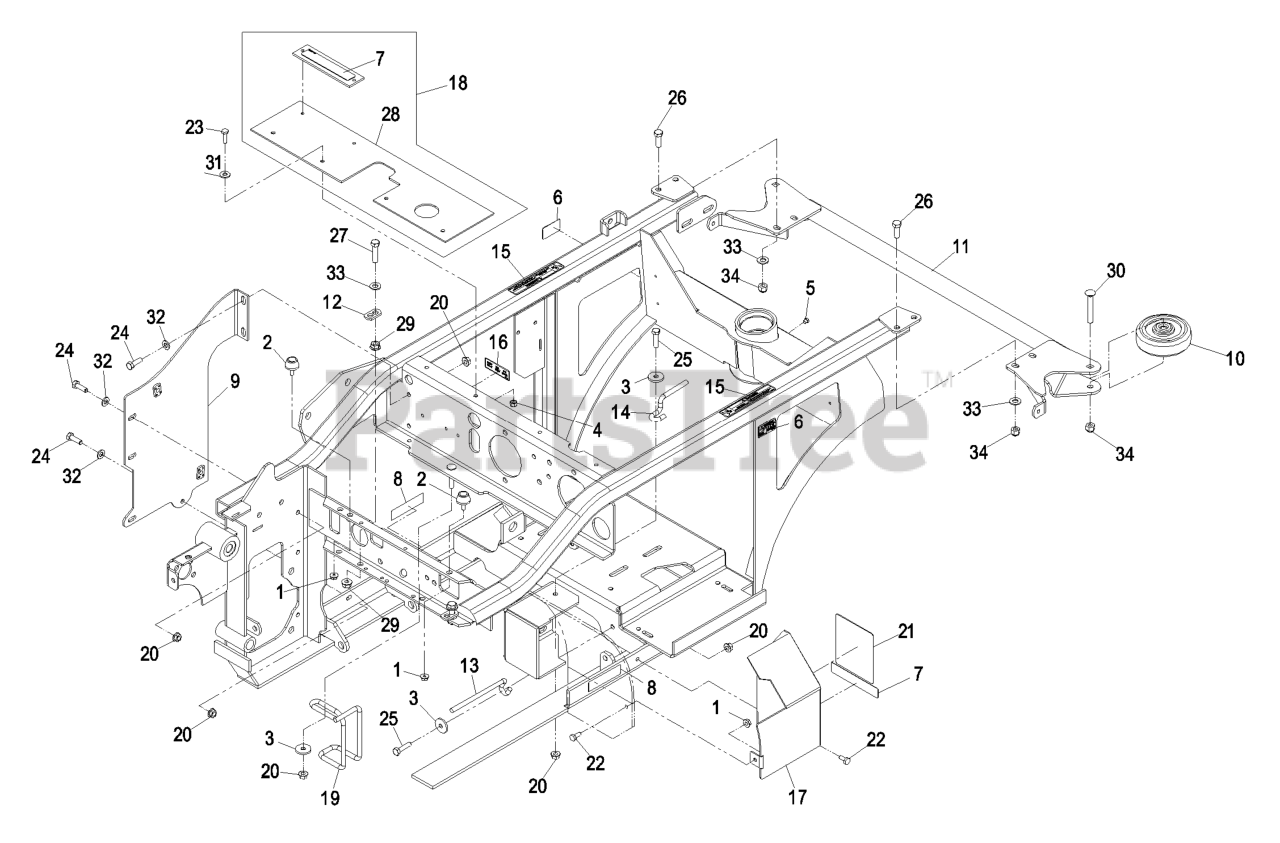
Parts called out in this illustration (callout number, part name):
4	NUT-LOCK, NI
6	DECAL-SURFACE, HOT
7	DECAL-WARNING
8	DECAL-COVER, MISSING
10	ROLLER-BUMPER
12	TAB,SPRING ANCHOR
13	GUIDE-BELT
14	GUIDE-BELT
15	DECAL,PINCH POINT
16	DECAL,RELAY
18	LIFT SHIELD ASM
19	GUIDE,BELT (PLATED)
21	DECAL,BELT ROUTING
22	SCREW-HH
23	SCREW-HH
24	SCREW-HH
25	SCREW-HH
26	SCREW-HH
27	SCREW-HH
29	NUT-HHF, WHIZ
30	SCREW-CARR
31	WASHER-FLAT
32	WASHER-PLAIN
33	WASHER-FLAT
34	NUT-LOCK, NI
